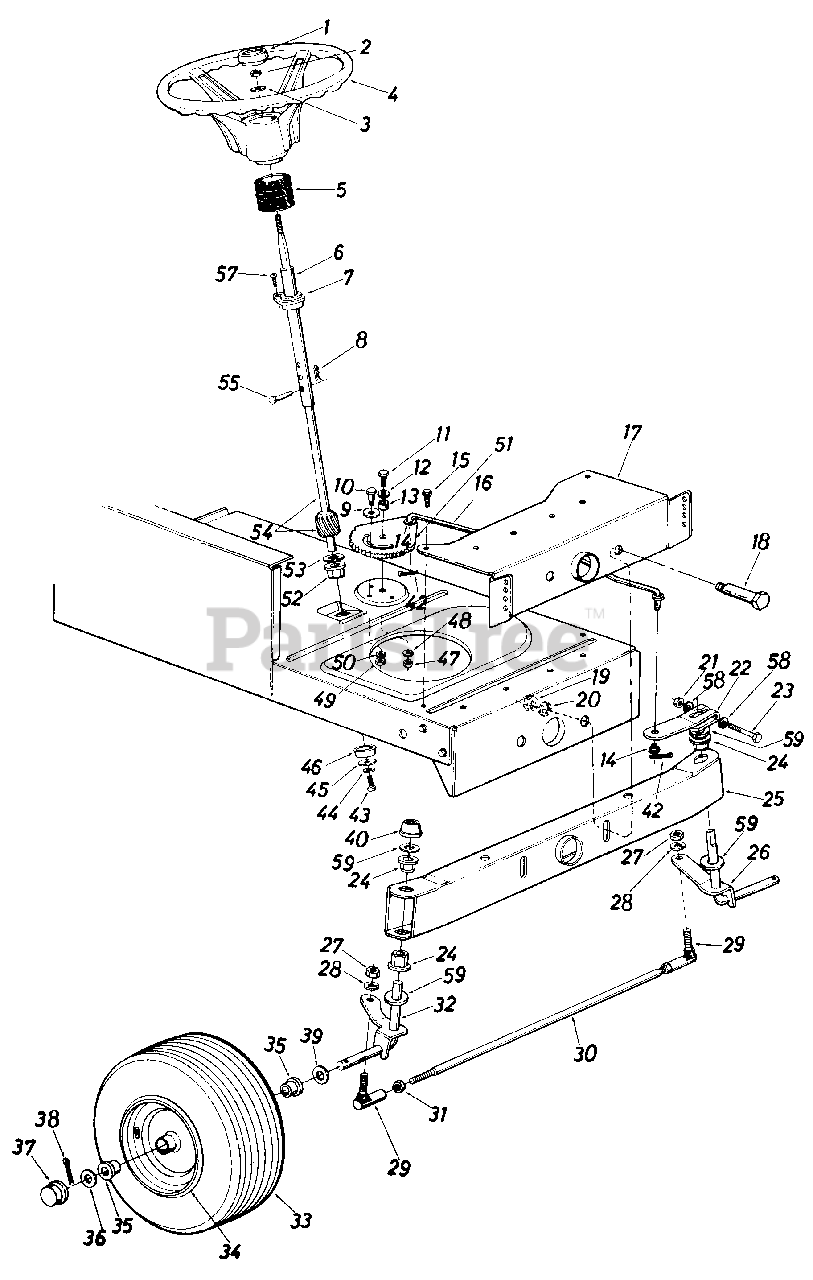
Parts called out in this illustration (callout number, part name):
1	Steering Wheel Cap
2	Hex Nut 5/16-18 Thd.
3	Belleville Wash. .345" I.D.
4	Steering Wheel
5	Steering Bellow 4.5"
6	Steering Column Ass'y.
7	Flange Bearing .890 I.D. x 1.36 O.D.
8	Internal Cotter Pin 1/4" Dia.
9	Fl-Wash. .438" I.D. x 1.37" O.D.
10	Shoulder Bolt .437" Dia. x .35 Lg. 5/16-18 Thd.
11	Hex Bolt 3/8-24 x 1.0" Lg. Grade 5
12	Fl-Wash. .38" I.D. x 1.0" O.D.
13	Spacer.380" I.D. x .625" O.D. x .227
14	Bushing
15	Hex Wash. Hd. Self-Tap Scr.
16	Steering Drag Link
17	Front Pivot Brk't.
18	Shoulder Bolt .498" Dia. x 2.04 Lg. 3/8-16 Thd.
19	Hex Nut 3/8-16 Thd.
20	L-Wash. 3/8" I.D.
21	Hex Cent. L-Nut 5/16-24 Thd.
22	Steering Arm Front Axle
23	Hex Bolt 5/16-24 x 2.00" Lg. Grade 5
24	Hex Flg. Brg. .634 I.D.
26	Front Axle Ass'y. L.H.
27	Hex Nut 3/8-24 Thd.
28	L-Wash. 3/8" I.D.
29	Ball Joi nt 3/8-24 Thd.
30	Tie Rod
31	Hex Jam Nut 3/8-24 Thd.
32	Front Axle Ass'y. R.H.
33	Wheel Ass'y. Comp.
34	Front Wheel Rim Only
35	Bearing
36	Fl-Wash. .635 I.D. x 1.591' O.D.
37	Front Wheel Hub Cap
38	Cotter Pin 118" Dia. x 1.25" Lg.*
39	Fl-Wash. .635" I.D. x 1.20" O.D.
40	Push Cap 5/8" Dia. Rod
42	Cotter Pin 118" Dia. x 1.0" Lg.
43	Hex L-Bolt 5/16-18 x .62" Lg.
44	L-Wash. 5/16" I.D.
45	Fl-Wash. .344" I.D. x 1.25" O.D.
46	Spacer (Plastic)
47	Hex Nut 3/8-24 Thd.
48	L-Wash. 3/8n l.D.*
49	Hex Nut 5/16-18 Thd.
50	L-Wash. 5/16" I.D.
51	Steering GearSegment
52	Hex Flg. Brg. .634 I.D.
53	Fl-Wash. (Hardened)
54	Steering Shaft Lower
55	Clevis Pin 1/4" Dia. x 1.00" Lg.
57	Oval Hd. Cr. Sunk Scr. #10 x 5/8" Lg.
58	Bell-Wash.
59	Fl-Wash. (Hardened)
